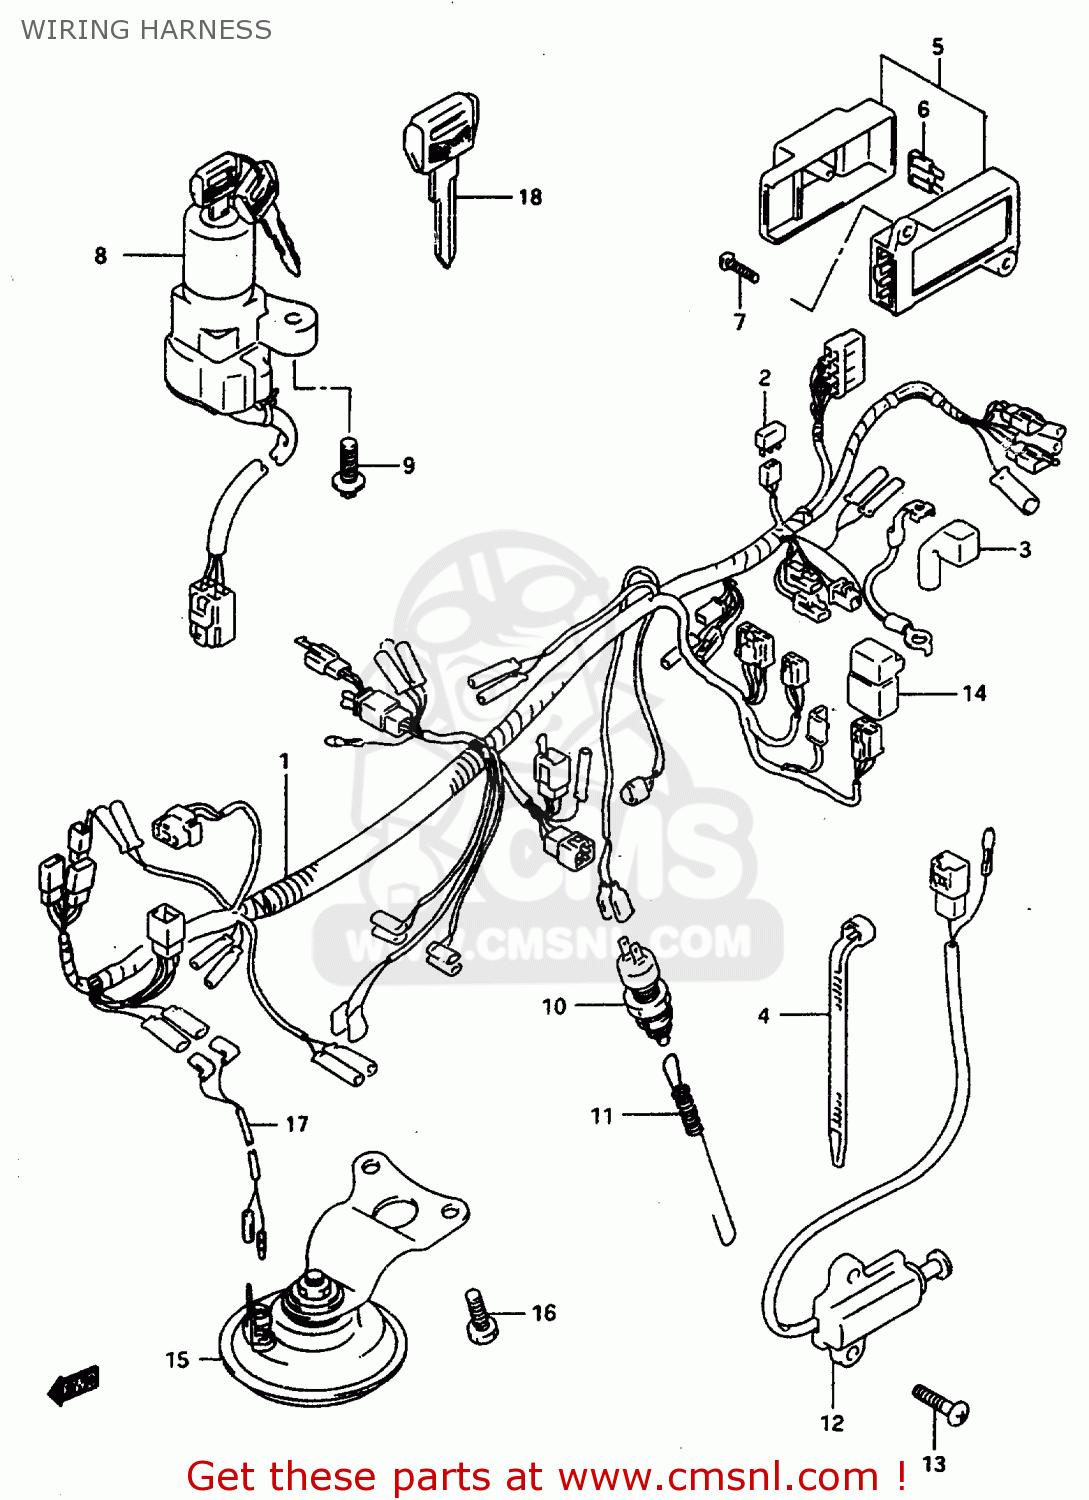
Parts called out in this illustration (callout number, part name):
1	HARNESS,WIRING
2	DIODE(STANLEY DE8804)
3	CAP,BATTERY PLUS TERMINAL
4	CLAMP(L:95)
5	BOX ASSY,FUSE
6	FUSE(10A)
7	SCREW
8	LOCK ASSEMBLY,STEERING
9	SCREW(6X18)
10	SWITCH ASSY,STOP LAMP
11	SPRING
12	SWITCH ASSY,SIDE STAND
13	BOLT
14	RELAY ASSY
15	HORN ASSY
16	BOLT
17	WIRE,CLUTCH LEAD
18	KEY,BLANK
